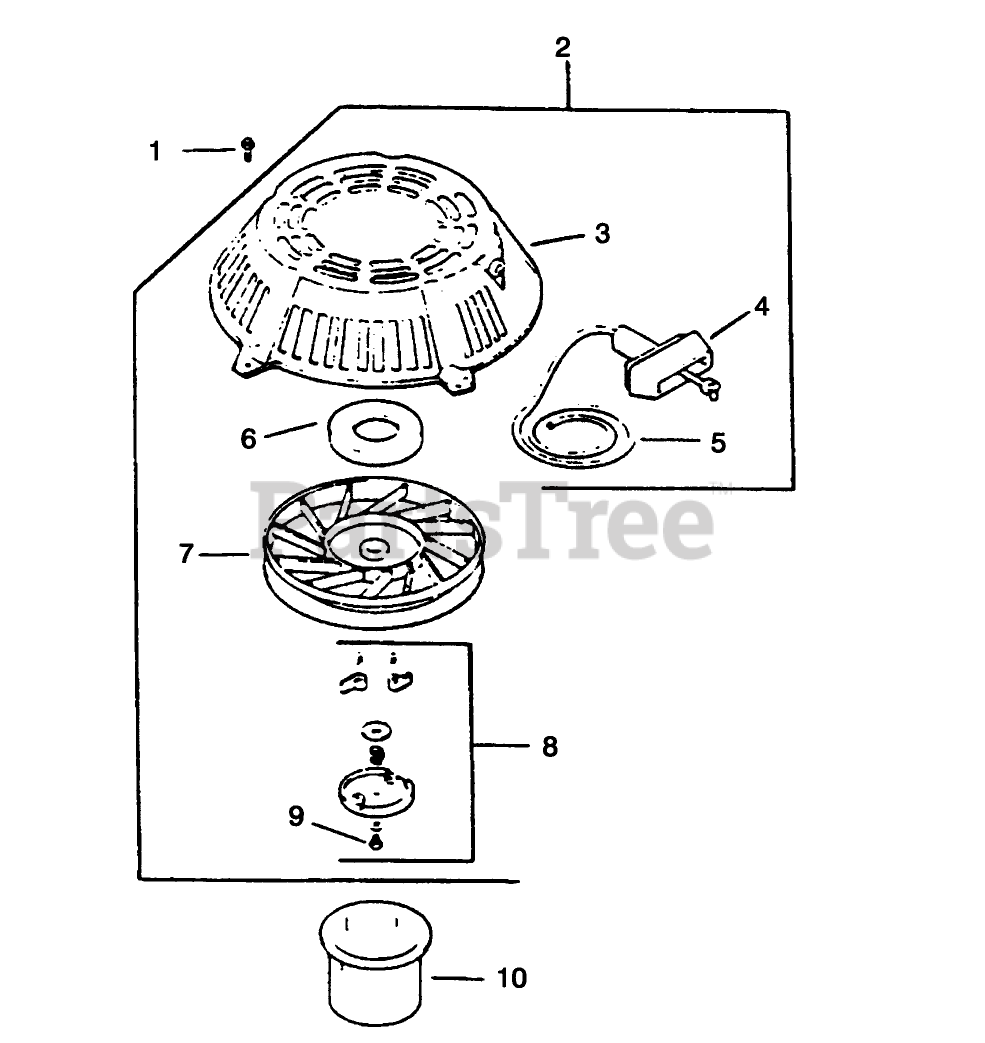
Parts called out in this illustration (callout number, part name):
2	Starter (Incl.Ref.#3-9)
3	Housing-Starter
4	Handle
5	Rope
6	Spring Keeper
7	Pullet
8	Kit-Dog Replacement
10	Cup-Drive
